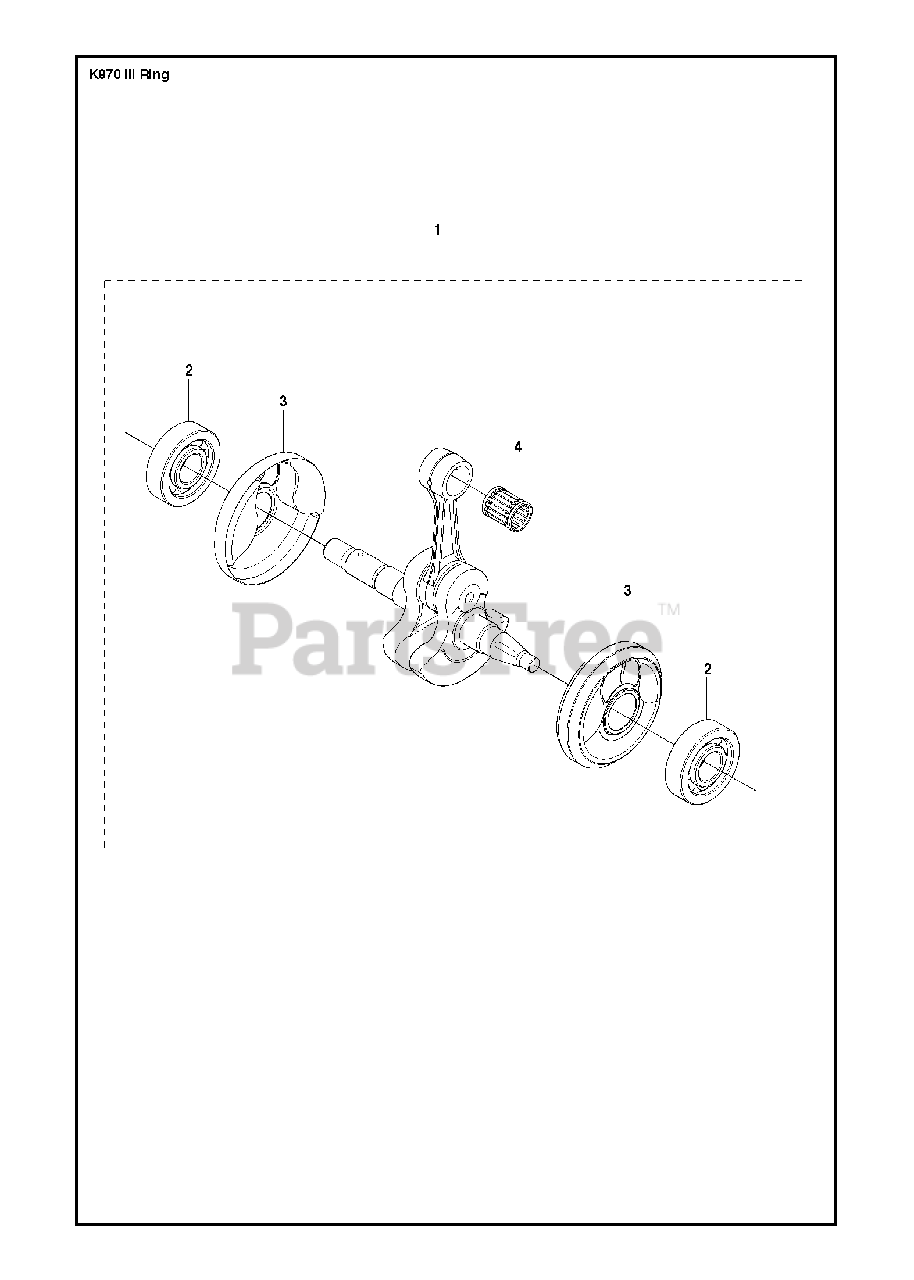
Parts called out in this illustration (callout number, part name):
1	CRANKSHAFT ASSYIncl. 2 - 4
2	BALL BEARING
4	NEEDLE BEARING
